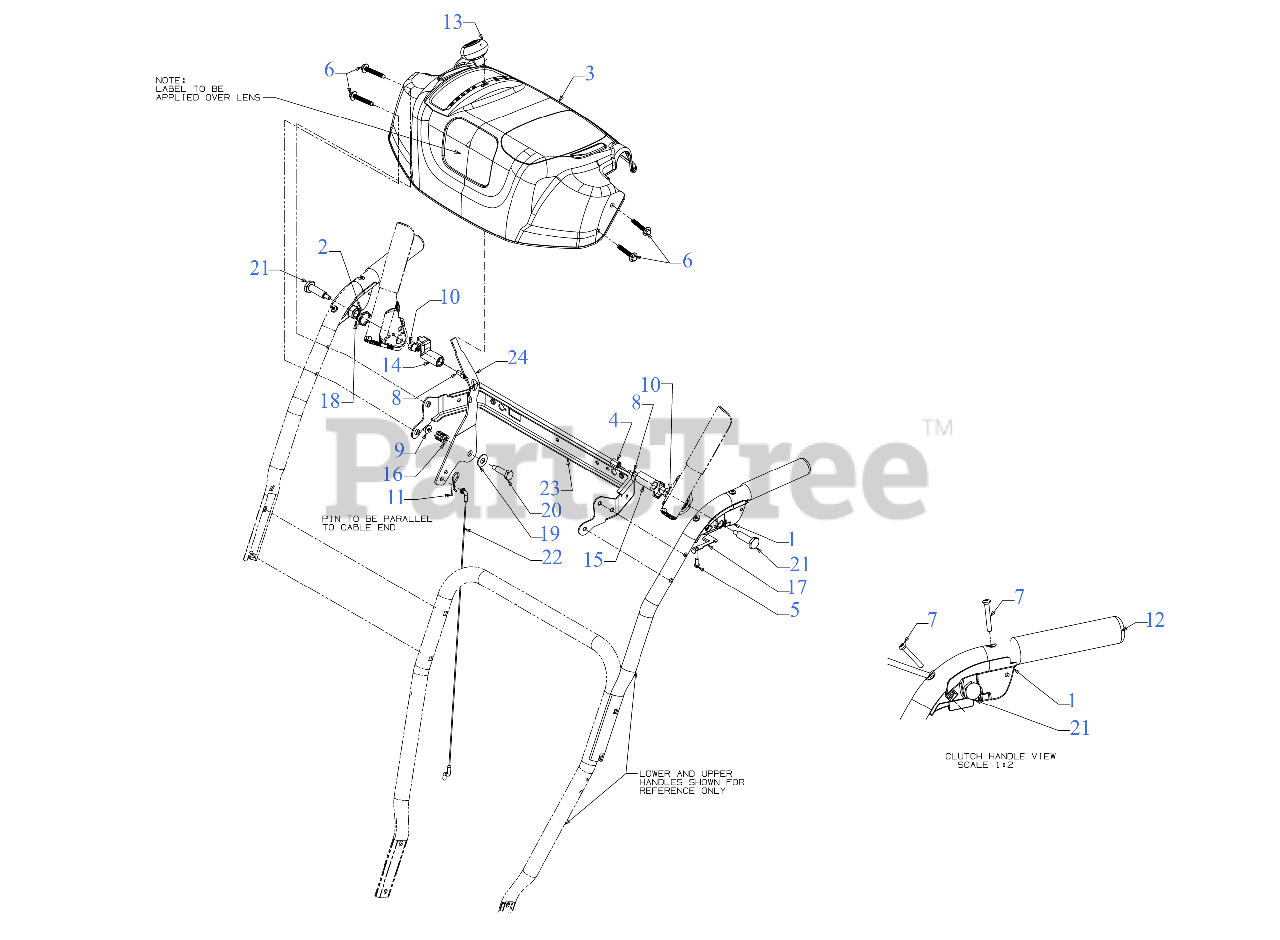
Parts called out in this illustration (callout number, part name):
1	CLUTCH LOCK HANDLE ASSEMBLY (LH)
2	CLUTCH LOCK HANDLE ASSEMBLY (RH)
3	HANDLE PANEL ASSEMBLY (BLACK)
4	PIVOT ROD
5	SCREW #8-16 x .50
6	SCREW 1/4-20 x 1.625
7	SCREW #10-24 x 1.375
8	SCREW 1/4-20 x .50
9	FLANGE LOCK NUT
10	HEX NUT W/PATCH
11	INTERNAL COTTER PIN
13	SHIFT KNOB
14	LOCK PLATE
15	CLUTCH LOCK CAM
16	COMPRESSION SPRING
17	CLUTCH SPRING
18	TORSION SPRING
19	FLAT WASHER .40X.88X.060
20	SHOULDER SCREW
21	SHOULDER SCREW .437 x 1.345 1/4-20
22	SPEED SELECTOR CABLE (PLASTIC)
23	HANDLE SUPPORT BRACKET (POWDER BLACK)
24	SHIFT LEVER
